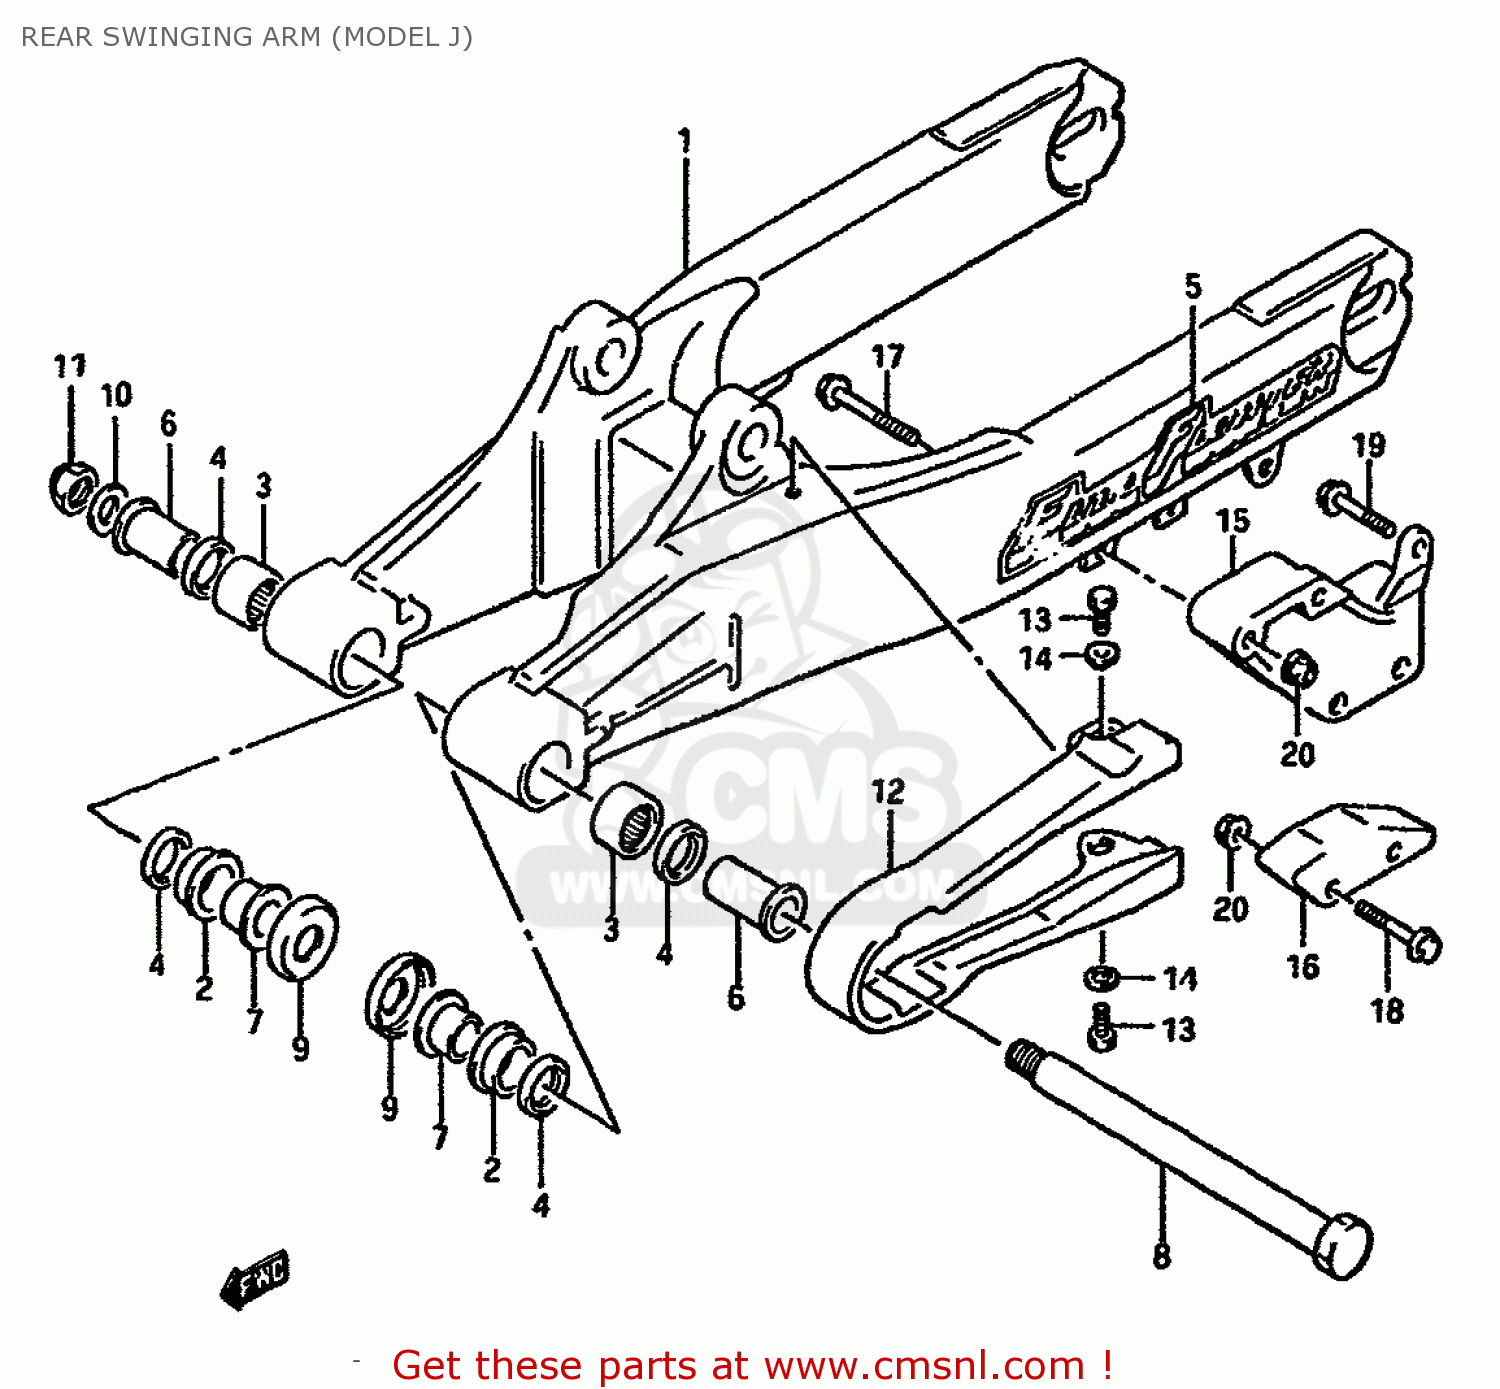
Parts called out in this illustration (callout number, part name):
1	SWING ARM ASSEMBLY,REAR
2	BUSHING,REAR SWING ARM PIVOT
3	BEARING(20X27X20)
4	OIL SEAL
5	LABEL (FRONT CARRIER WARNING)
6	SPACER,RR SWGARM PIVOT
7	SPACER,RR SWGARM PIVOT INNER
8	SHAFT,REAR SWING ARM PIVOT
9	COVER,RR SWGARM DUST SEAL
10	WASHER(14.2X24X2.3)
11	NUT
12	BUFFER,CHAIN TOUCH DEFENSE
13	BOLT
14	WASHER
15	GUIDE,CHAIN
16	DEFENSE,CHAIN GUIDE
17	BOLT
18	19
19	BOLT 6X20
20	NUT
21	NUT 8MM
22	PIN 20X20
23	GUIDE,CHAIN
24	GUIDE,CHAIN
25	DEFENSE,CHAIN GUIDE
26	BOLT
27	BOLT,UNDER
28	NUT
29	BOLT,REAR
